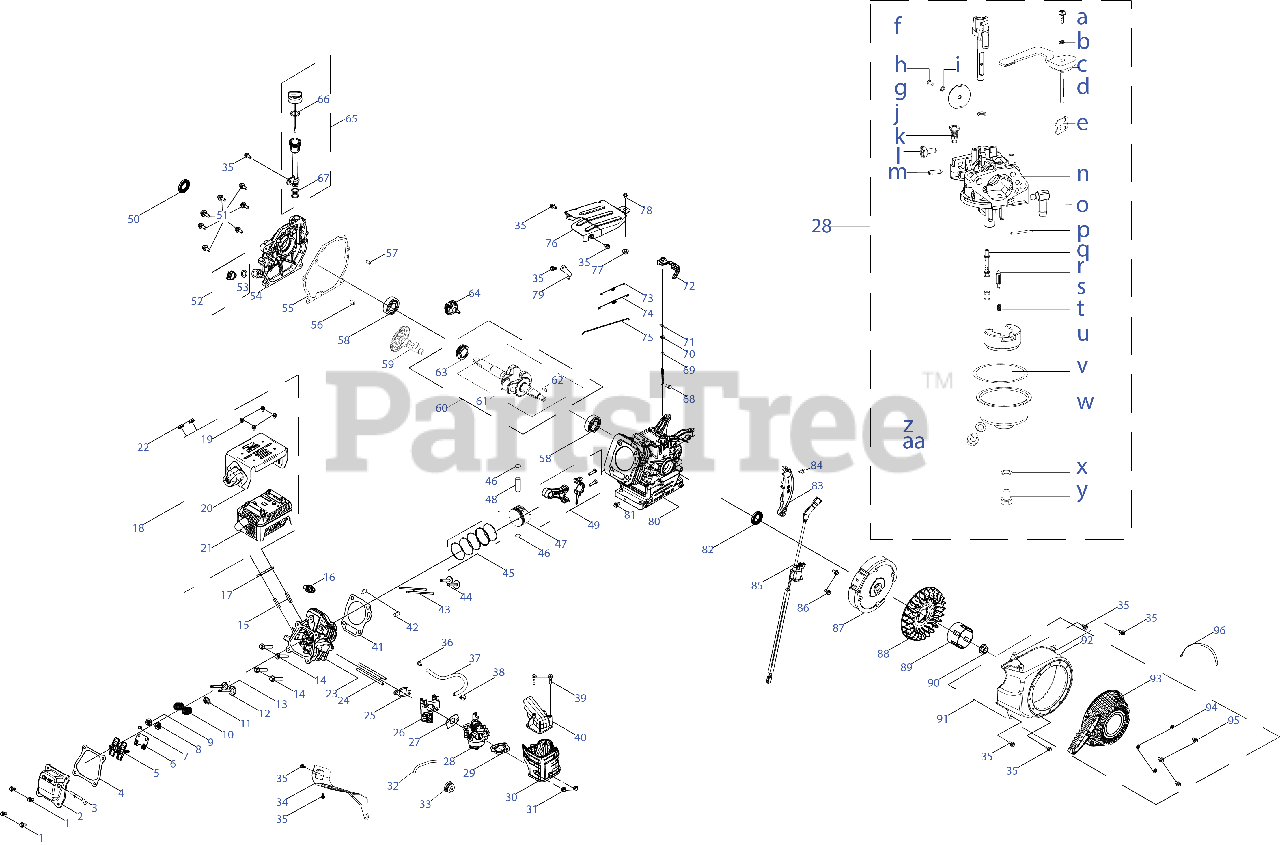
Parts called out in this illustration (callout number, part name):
1	BOLT M6 x 16
2	VALVE COVER
3	BREATHER HOSE
4	VALVE COVER GASKET
5	ROCKER ARM ASSEMBLY
6	ROCKER ARM BASE
7	EXHAUST VALVE ADJUSTER
8	INTAKE VALVE SPRING RETAINER
9	EXHAUST VALVE SPRING RETAINER
10	VALVE SPRING
11	INTAKE VALVE SEAL
12	INTAKE VALVE
13	EXHAUST VALVE
14	BOLT M8-1.25 x 55 GR10.9
15	STUD M8 x 36
16	SPARK PLUG
17	MUFFLER GASKET
18	MUFFLER ASSEMBLY
19	BOLT M5-.8 x 8 CL10.9
20	OUTER MUFFLER SHIELD
21	MUFFLER ASSEMBLY
23	CYLINDER HEAR ASSEMBLY 179/208
24	STUD M6-1 x 110 GR8.8
25	CARBURETOR INSULATOR GASKET
26	CARBURETOR INSULATOR
27	CARBURETOR GASKET
28	CARBURETOR ASSEMBLY HY-170-JA
29	CARBURETOR GASKET PLATE
30	HEATER BOX HOUSING
32	FUEL HOSE 3.2X6.5X530
34	AIR SHIELD
35	BOLT M6-1 x 12 GR8.8
38	HOSE CLAMP
39	BOLT M4.2 x 16
40	INTAKE HEATER BOX
41	CYLINDER HEAD GASKET
43	PUSH ROD
45	PISTON RING SET
46	PISTON PIN SNAP RING
48	PISTON PIN
49	CONNECTING ROD ASSEMBLY
50	OIL SEAL
51	BOLT M8-1.25 x 32 GR5.8
53	O-RING 15.8 x 2.5
54	CRANKCASE COVER
55	CRANKCASE COVER GASKET
56	DOWEL PIN
57	DOWEL PIN
60	CRANKSHAFT ASSEMBLY
61	CRANKSHAFT
62	FLYWHEEL KEY
63	DRIVE TIMING GEAR
64	GOVERNOR GEAR/SHAFT ASSEMBLY
65	DIPSTICK ASSEMBLY
66	DIPSTICK O-RING
67	OIL FILL TUBE O-RING
68	GOVERNOR SHAFT
70	GOVERNOR SEAL
71	COTTER PIN
72	GOVERNOR LEVER
73	GOVERNOR SPRING
74	THROTTLE RETURN SPRING
75	GOVERNOR ROD
76	GOVERNOR SHIELD
78	BOLT-M6-1 x 28 GR8.8
79	GOVERNOR SPRING BRACKET
81	OIL PLUG 1/8 NPT
82	OIL SEAL
83	LOWER SHIELD
84	SCREW M6-1 x 20 CL5.8
85	IGNITION COIL ASSEMBLY
86	BOLT M6-1 x 25 GR8.8
88	COOLING FAN
89	STARTER CUP
90	FLYWHEEL NUT
91	RECOIL STARTER ASSEMBLY
92	BLOWER HOUSING
93	RECOIL STARTER HOUSING
94	RECOIL FLAT WASHER
95	BOLT M6 x 10
96	CABLE TIE - 3 x 150
